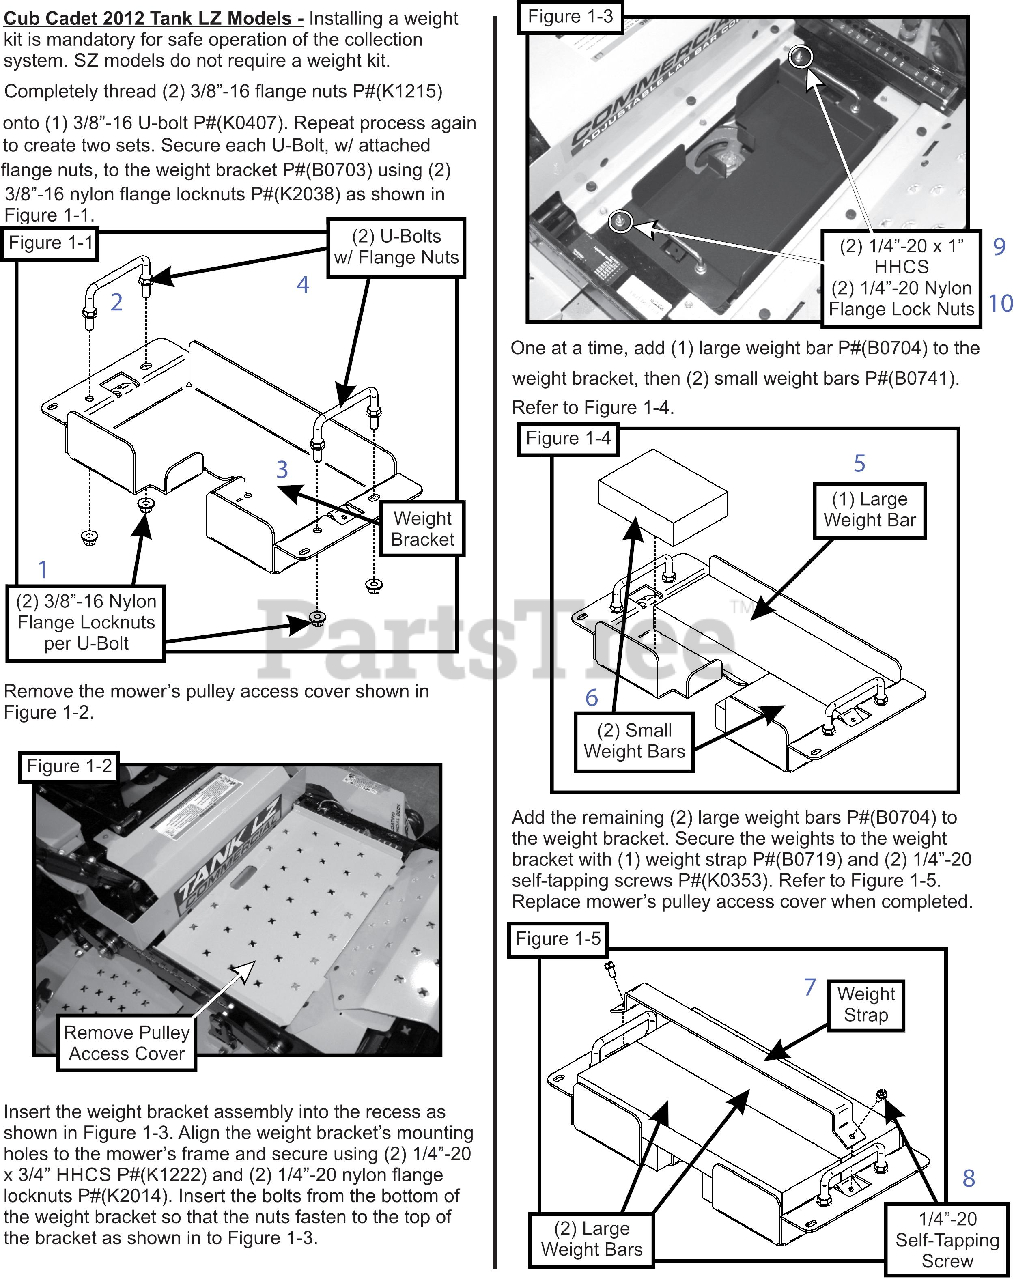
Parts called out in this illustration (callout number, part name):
1	Flange-3/8-16
2	U-Bolt 3/8-16"
3	Weight Bracket
4	Locknut-Nylon Flan
5	Weight Bar-14"
6	Weight Bars-Small
7	Weight Strap
8	Hex Screw Head 1/4-20 X 1/2"
9	Hex Screw Head 1/4-20 X 3/4"
10	Locknut-Nylon 1/4-20"
